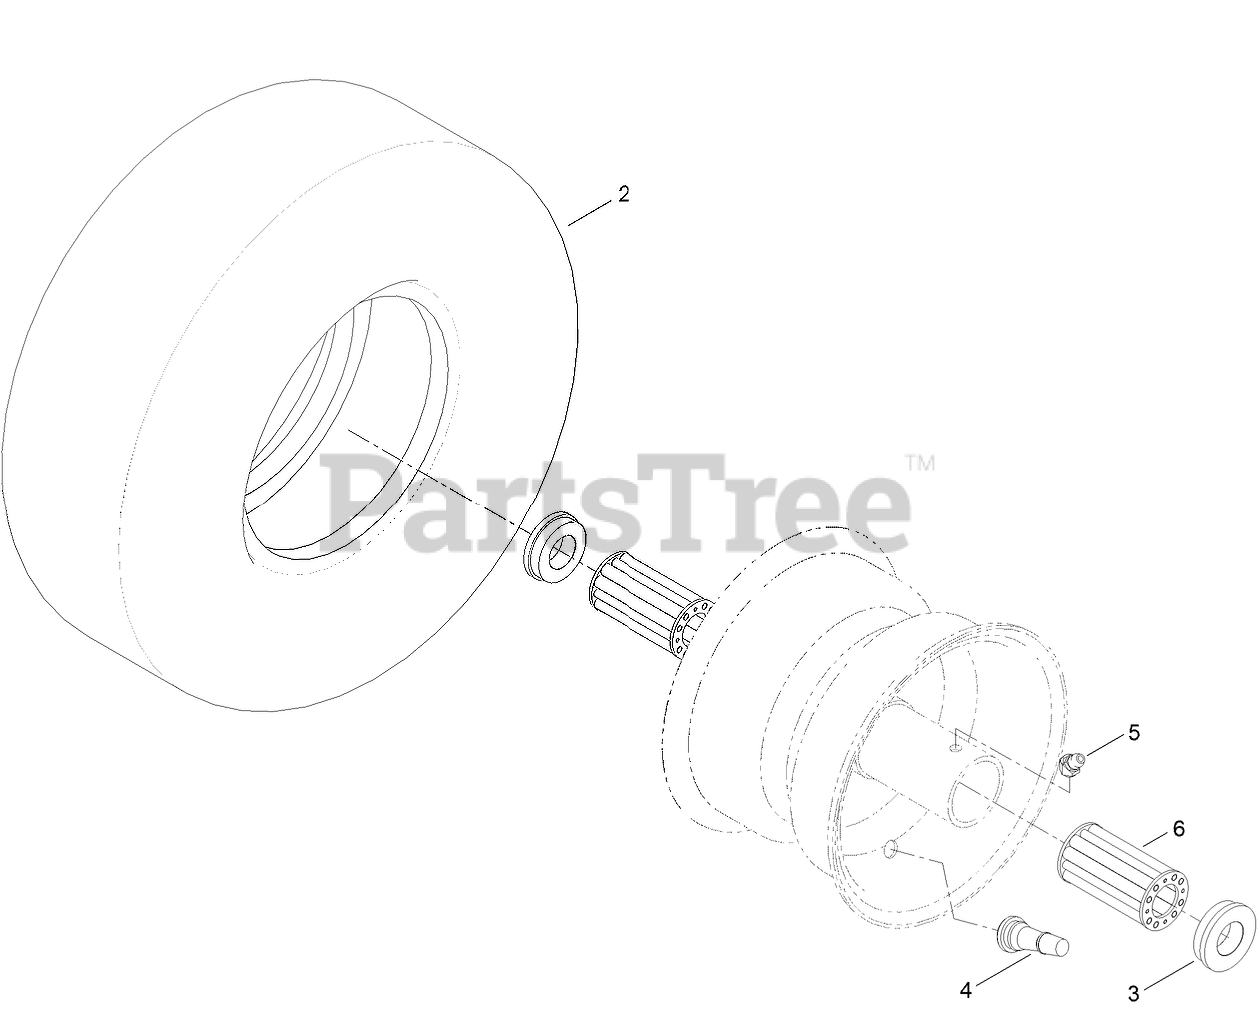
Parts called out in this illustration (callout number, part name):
3	BUSHING-FLANGE
4	VALVE
5	FITTING-ZERK
6	BEARING
